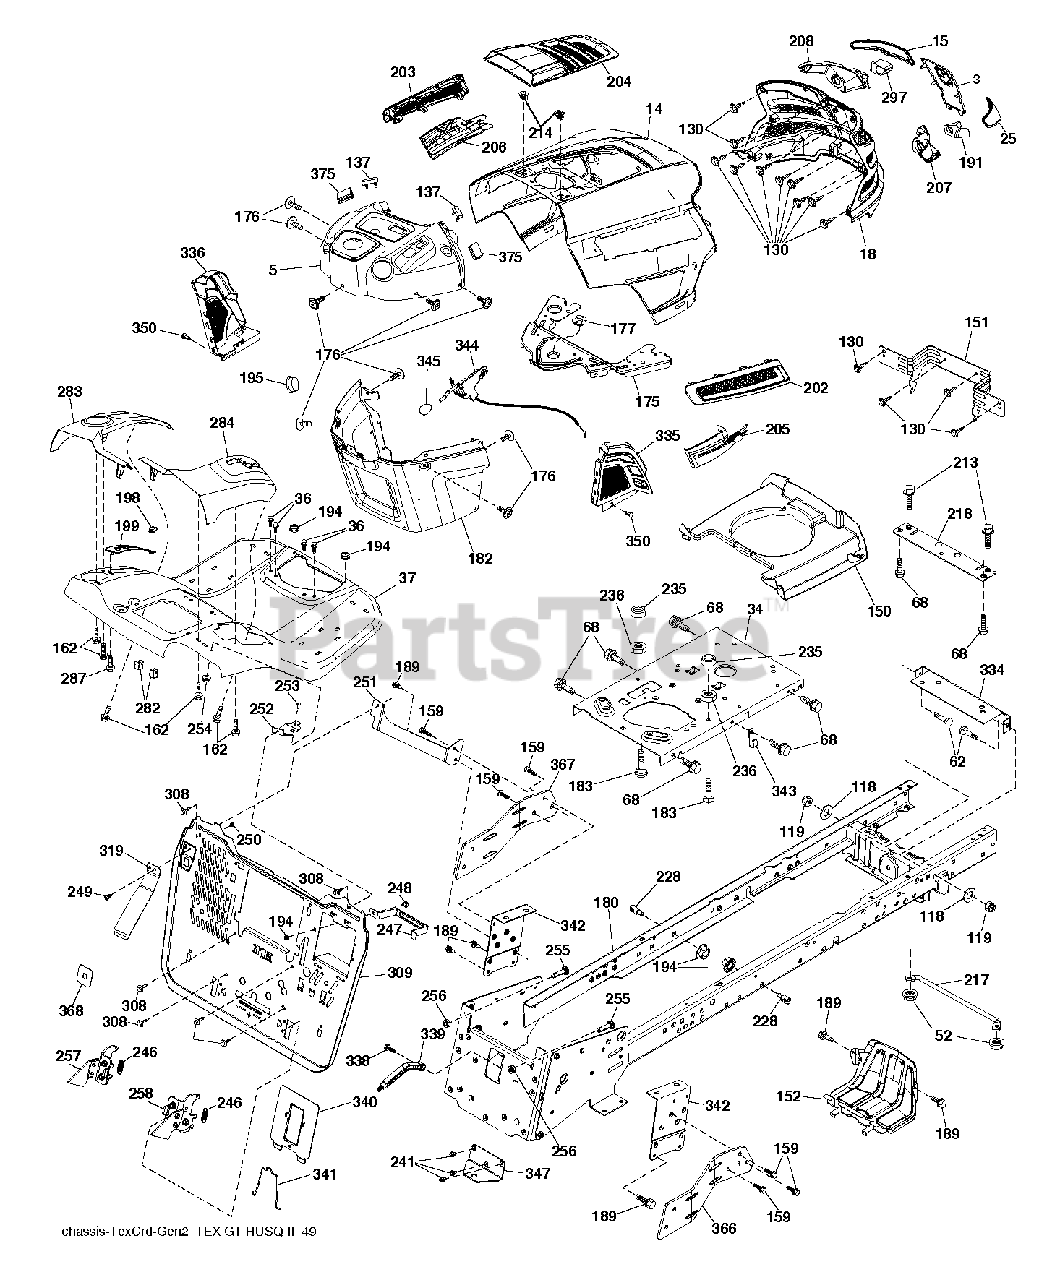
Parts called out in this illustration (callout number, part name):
3	APPLIQUE.SUBASM.GT.HUSQ.II
5	UPPER.GT2.SVC.MINDING.PTO.H.
14	HOOD.ASM.HUSQVARNA.GT.TEX.ORAN
15	LENS.HEADLIGHT.LH.GTII.2011
18	GRILLE.SUBSTRATE.2011.
25	LENS.HEADLIGHT.RH.GTII.2011
34	PLATE.ENGINE.10GA.CRD.GENII
36	SCREW 5/16"
37	FENDER.TEX.SRD.CRD.BASE
52	LOCKNUT
62	BOLT D
68	SCREW LT
118	WASHER
130	SCREW.#10 X 0.750.BOS
137	BUMPER DASH
150	AIR.DUCT.GTV.BLACK
151	BRACKET.PIVOT.HOOD.GT.HUSQ.II
152	SHIELD.BROWNING.PNT.GT.V2
159	SCREW, 3/8-16X3/4
162	SCREW.HI-LO.CONSOLE
175	PLATE.CROSSMEMBER.HUSQ
176	SCREW.#10-24X5/8.RN.QU
177	BUSHING STEERING
180	WELDMENT.CHASSIS.TEX.CRD.GEN.2
182	DASH DASH LOWER
183	BOLT.5/16-18X1-1/4 FULL THD
189	SCREW
191	INSERT.REFLECTIVE.RH.HUSQ.GTII
194	NUT LOCK HEX FLANGE 5/16-18
195	PLUG.HOLE.DASH.LOWER.12V.BLK
198	INDICATOR.DECK.LIFT.RED
199	PLATE DECK LIFT
202	VENT.SIDE.RH.GT.HUSQ.II.
203	VENT.SIDE.LH.GT.HUSQ.II.498
204	VENT.TOP.HUSQ.GT2
205	SIDE.TRIM.RH.GT.HUSQ.II
206	SIDE.TRIM.LH.GT.HUSQ.II.GRAY
207	BEZEL LIGHT.RH.GT.II.MYLAR
208	BEZEL LIGHT.LH.GT.II.MYLAR
213	BOLT
214	CLIP.RETAINER.TINNER.
217	ROD.PIVOT.HOOD
218	X-PIECE.HOOD.STOP.NON/
228	STUD.FASTNER.W/ANTI-ROTATE
235	SPACER FENDER
236	NUT.CENTERLOCK.5/16-
241	SCREW 5/16-18X1
246	SPRING.TCRD.GEN2.5.BAGGER.EXT
247	STRAP.BATTERY.TCRD.GE
248	BOLT
249	SCREW.BUTTONHD.10-24X1/2.(2 2)
250	NUT 10-24 NYLOC
251	BRACKET.PNT.LH.SUPP.B
252	BRACKET.PNT.RH.SUPP.B
253	BOLT
254	NUT T
255	BOLT.CROSSDRILLED.381
256	Hex Nut, 3/8-16
257	LATCH.ASM.BGR.LH.GEN2
258	LATCH.ASM.BGR.RH.GEN2
282	CLIP.RETAINER.CONSOLE.LT.HUSQ
283	CONSOLE.DECKLIFT.CRDII.498
284	CONSOLE.PEDAL.HYDRO
287	SCREW 1/4X20
297	INSERT.REFLECTIVE.LH.HUSQ.GTII
308	BOLT, 5/16-18 X 1 3/4
309	BACKPLATE.TEXCRD2.5.B
319	LEVER.BAG.CRDII.ANTIROTATION
334	BRACKET.ENGINE
335	COVER.LOWER.DASH.RH.BLACK
336	COVER-LH.LOWER.DASH.GT2.BLACK
338	BOLT BOLT SHOULDER
339	LEVER LEVER BAGGER
340	BATTERY.DOOR.TCRD.GEN
341	LATCH.BATTERY.DOOR.TC
342	SUPPORT.PNT.FENDER.CRD.TEX
343	CLIP CLIP
344	CONTROL.EZ.MULCH.TEX/CRD
345	RP KNOB.OVAL.TAPERED.3/8-16BLK
347	HITCH HITCH TOW TEX CRD GEN 2
350	CLIP.X-MAS.TREE
366	BRACKET.RH.FRONT.BAGGER.BLACK
367	BRACKET.LH.FRONT.BAGGER.BLACK
368	FULL.LEVER.BAGGER.TEX.CRD
375	BUMPER CLIP-ON. DASH 1"
